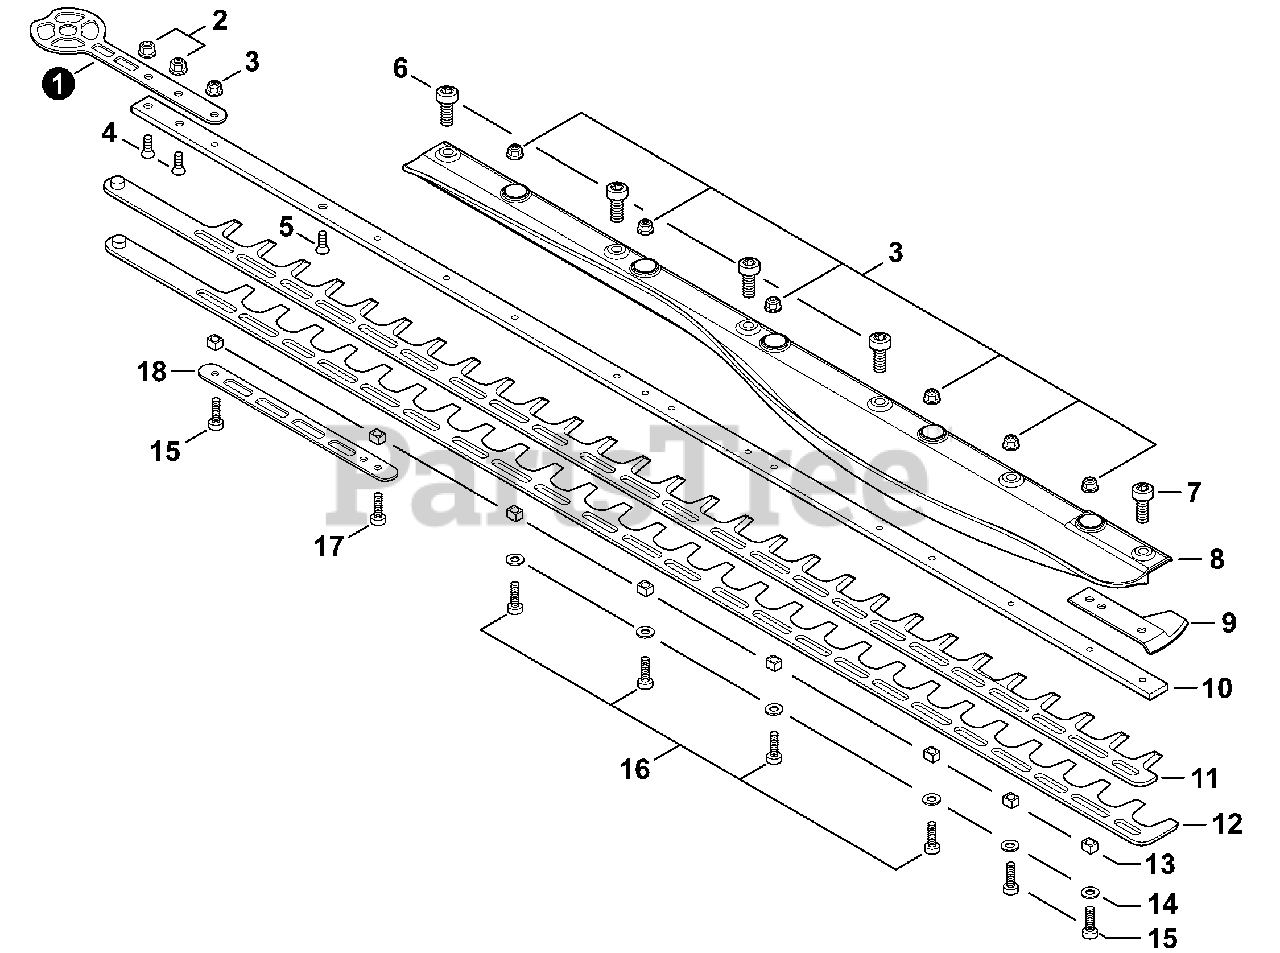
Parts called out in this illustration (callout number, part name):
2	NUT, FLANGE M6
3	NUT, FLANGE M5
4	BOLT 6×30
5	BOLT 6×25
6	BOLT, TORX 5×8
7	BOLT, TORX 5×10
8	DEFLECTOR, DEBRIS
9	GUARD, TIP
10	SUPPORT, BLADE 40"
11	BLADE, UPPER 40"
12	BLADE, LOWER 40"
13	COLLAR 5
15	BOLT, TORX 5×25
16	BOLT, TORX 5×20
17	BOLT, TORX 5×30
18	PLATE, EYE
